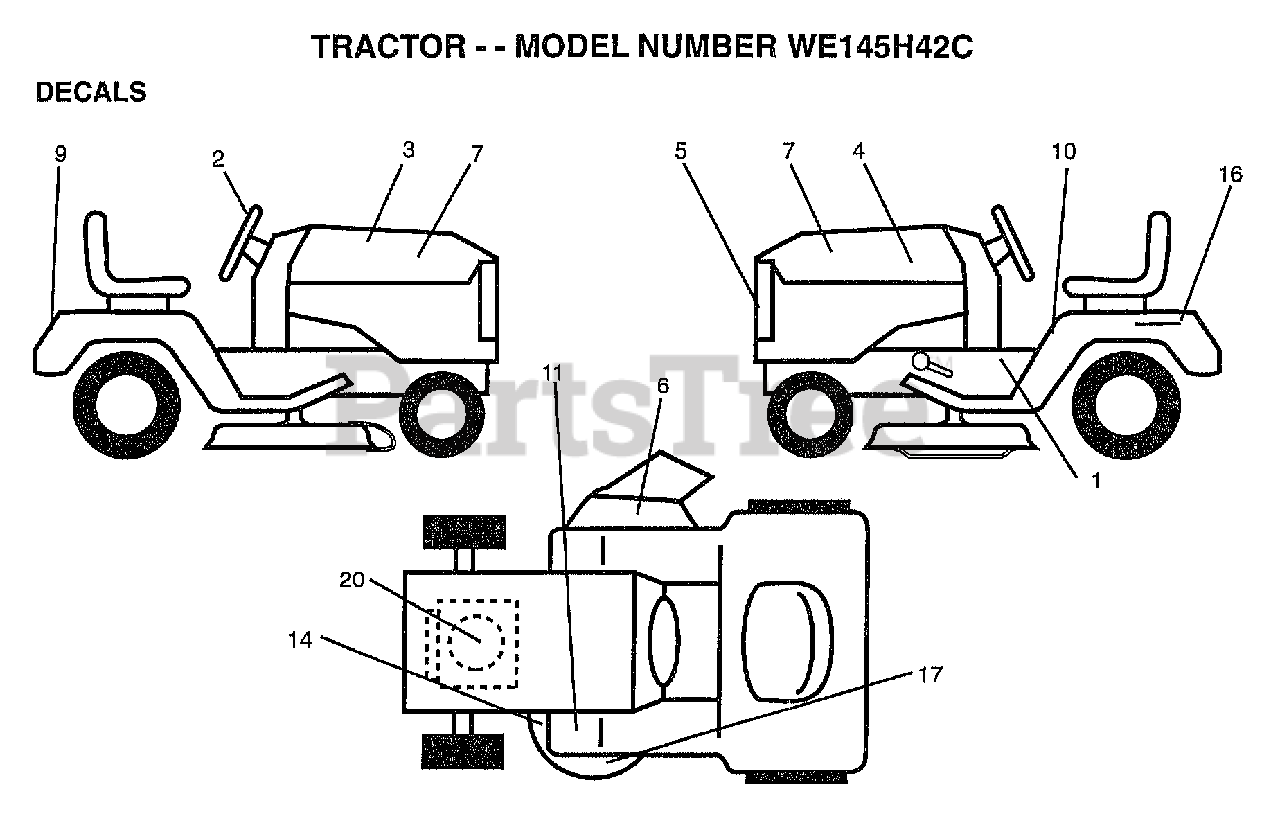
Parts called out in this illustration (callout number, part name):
1	DECAL SADDLE OPER
2	DECAL, INS STRG WH
3	DECAL.HOOD.RH.
4	DECAL.HOOD.LH
5	DECAL, GRILLE LENS
6	"DECAL, WARNING"
7	DECAL.PANEL.SIDE
9	DECAL.FENDER.LOGO
10	DECAL.CAUT.ENG/FR
11	DECAL T
14	"DECAL-SCHEM,BELT"
16	DECAL.BATRY.3-3908
17	DECAL, DECK GRASSEATER
20	DECAL, ENGINE
